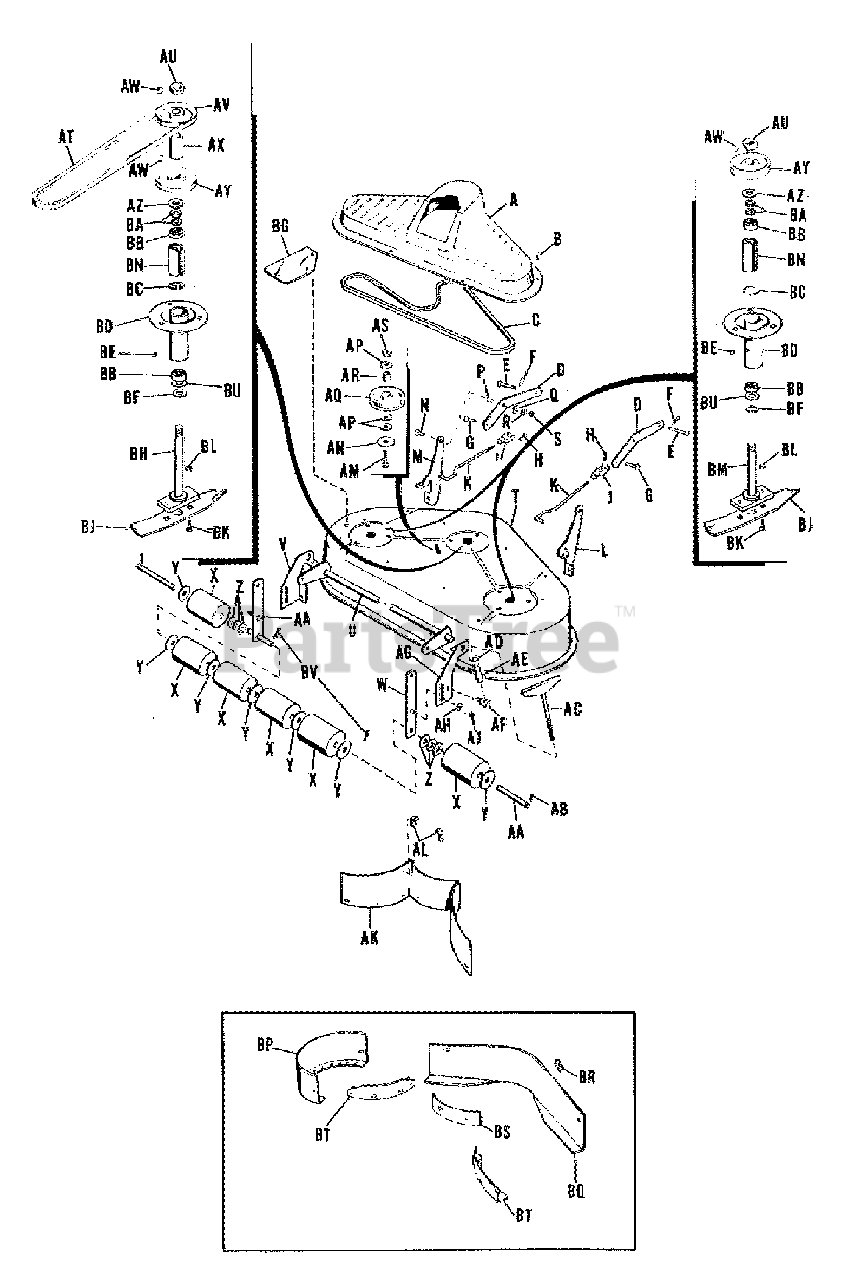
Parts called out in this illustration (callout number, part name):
A	COVER, Housing
B	SCREW, Self-Tapping, Hex Head 1/4-20 x 3/8
C	V-BELT, Mower Spindle Drive
D	LEVER, Front
F	CLIP, Spring
G	PIN,Clevis
H	PIN,Cotter 3/32 x 3/4
J	CLEVIS, Adjustment
K	ROD, Height Adjustment
L	BRACKET, Front, R.H.
M	BRACKET, Front, L.H.
N	CAPSCREW, Hex Head, 3/8-16x1
Q	WASHER, Plain, 3/8
R	WASHER, Lock, 3/8
S	NUT, Full Hex, 3/8-16
U	LEVER ASSEMBLY, Rear
V	BRACKET, Roller, L.H.
W	BAR ASSEMBLY, Roller
AA	BAR & SHAFT ASSEMBLY
AB	PIN, Cotter
AC	SCREW ASSEMBLY, Adjustment
AD	WASHER, Plain
AE	SOCKET ASSEMBLY, Crank
AG	BRACKET, Roller R.H.
AH	WASHER, Plain, 5/16
AJ	NUT, Hex, Full Lock 3/8
AL	CLIP, Baffle
AM	BOLT, Carriage, 3/8-16 x 1
AP	WASHER, Plain, 5/16
AQ	PULLEY IDLER
AS	NUT, Hex, Full Lock 3/8 - 16
AT	V-BELT, Cross Drive
AU	NUT, Hex Jam, Center Lock 3/4 - 16
AV	PULLEY, Cross Drive
AW	WOODRUFF KEY, 3/16 x 5/8, #61
AY	PULLEY IDLER
BC	RING, Backing
BD	TUBE ASSEMBLY, Arbor
BG	DEFLECTOR
BH	ARBOR ASSEMBLY, Drive
BM	ARBOR ASSEMBLY
BV	COTTER PIN
BP	BAFFLE, Side
BQ	BAFFLE, Mulcher, Front
BS	BAFFLE, Rear Center
BT	BAFFLE, Mulcher, Rear, Side
